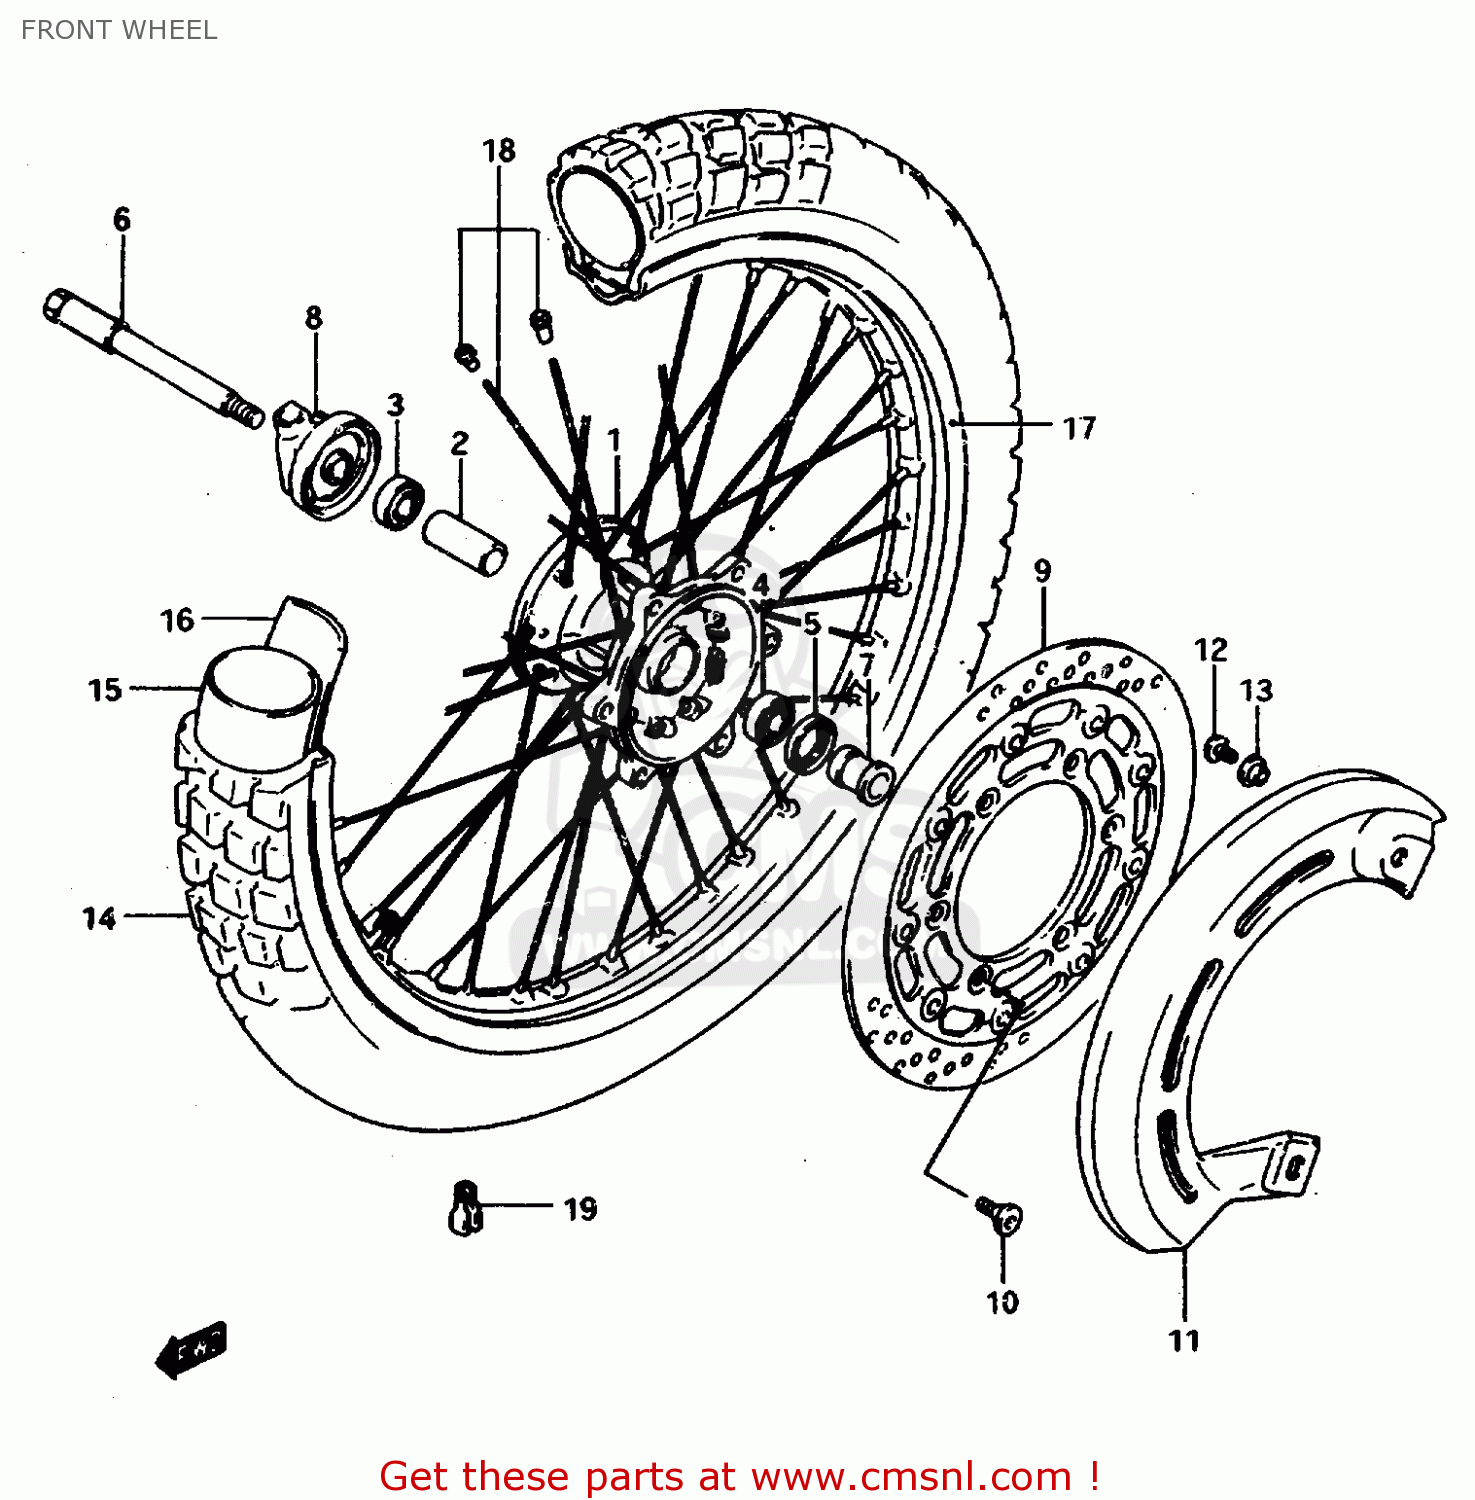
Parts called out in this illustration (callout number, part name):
1	HUB,FR WHEEL
2	SPACER,FR HUB BEARING
3	BEARING
4	BEARING
5	SEAL,OIL(22X35X5)
6	AXLE,FR
7	SPACER,FR AXLE,L
8	BOX ASSY,SPEEDOMETER GEAR
9	DISC,FR BRAKE
10	BOLT,BRAKE DISC
11	COVER,FRONT BRAKE DISC
12	SCREW 6X12
13	WASHER
14	TIRE,90/90-21
15	TUBE
16	PROTECTOR,WHEEL INNER
17	RIM,FR WHEEL(21X1.85)
18	SPOKE SET,FR WHEEL
19	BALANCER,WHEEL
